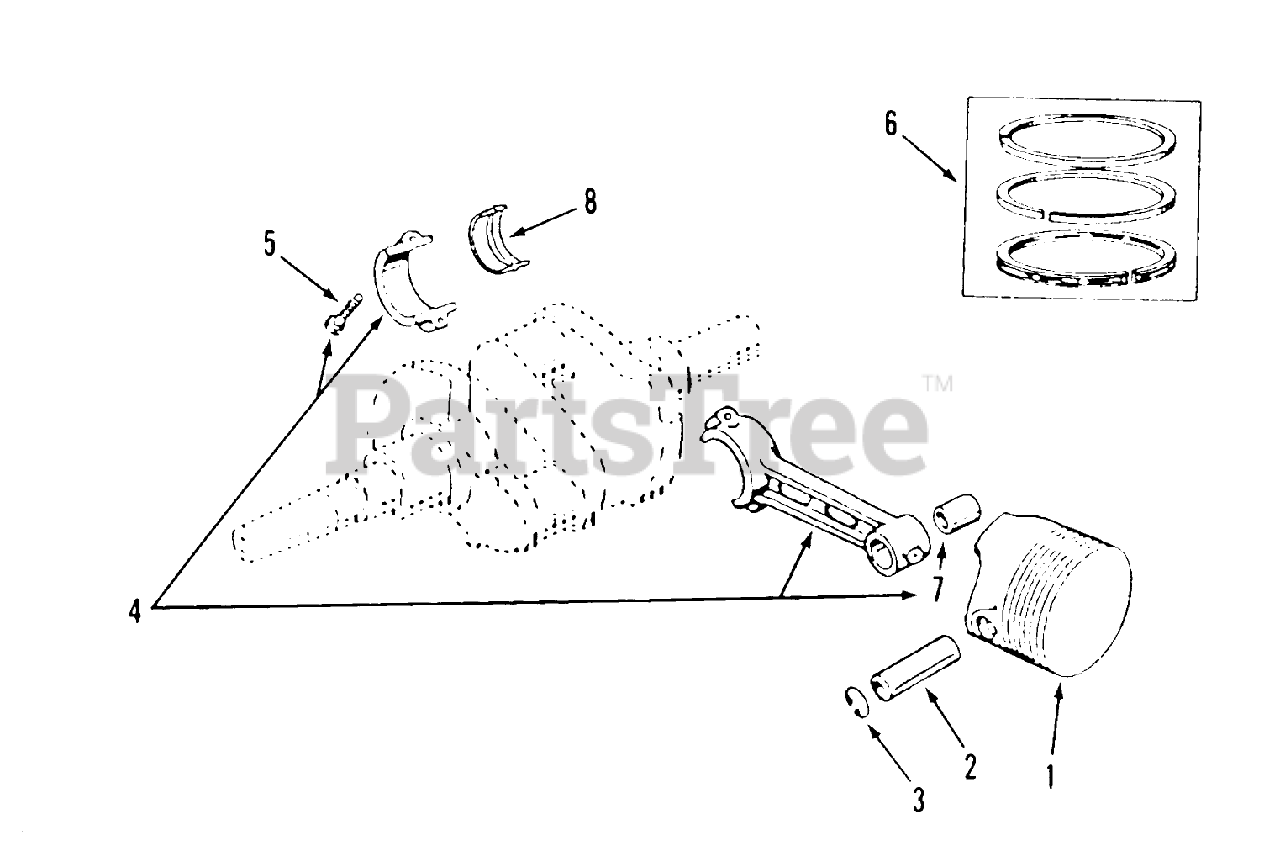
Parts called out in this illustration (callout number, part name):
1	Piston Pin (Incl. Pin Retaining Ring)
2	PIN-PISTON
4	ROD-CONNECTING
5	BOLT-PLACE
6	PISTON RING KIT
7	BUSHING-PISTON PIN
8	Bearing-Connecting Rod, Half
